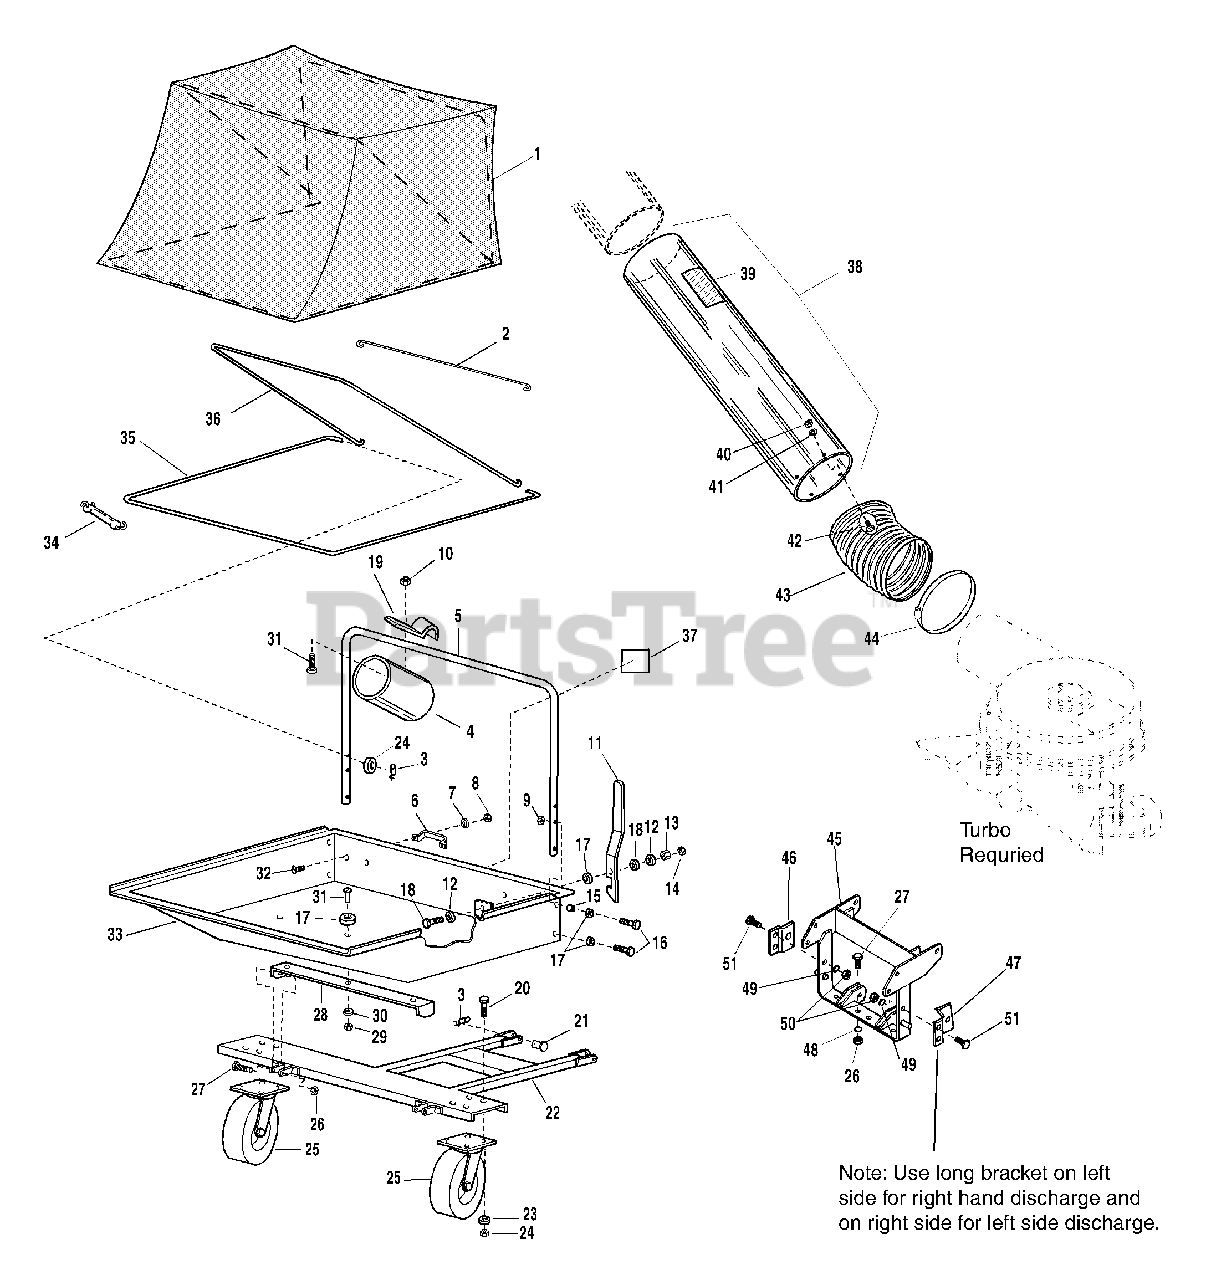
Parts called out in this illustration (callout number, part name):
1	COVER, Jrco, Cart
3	SAFETY, Pin
5	TUBE, Support
6	HANDLE, Lift
7	LOCKWASHER, Spring, 1/4-20
8	NUT, Hex, 1/4-20
9	NUT, Hex Centerlock, 5/16-18
10	NUT, Hex Nylock, 1/4-20
11	HANDLE, Latch
12	WASHER, Compression
13	NUT,Hex, 5/16-18
14	NUT, Hex Jam, 5/16-18
16	CAPSCREW, Hex Head, 5/16-18 X 1-1/2
17	WASHER, 5/16
18	CAPSCREW, Hex Head, 5/16-18 X 1-1/4
19	SLEEVE, Clamp
20	CAPSCREW, Hex Head 3/8-16 X 1
21	PIN, Rnd, Head, Drilled, 1/2 X 1-1/2
22	FRAME, Jrco, Cart
23	WASHER, 3/8
24	NUT, Hex Centerlock, 3/8-16
25	WHEEL Assembly, Swivel
26	NUT, Hex Centerlock, 1/2-13
27	CAPSCREW, Hex Head, 1/2-13 X 1-1/4
28	BRACKET, "U"
29	NUT, Hex, 5/16-18
30	LOCKWASHER, Spring, 5/16
31	SCREW, Truss Head Slotted, 5/16-18 X 3/4
32	CAPSCREW, Hex Head, 1/4-20 X 1/2
33	BOX, Jrco 44"
34	STRAP, Rubber
36	ROD, Support
37	DECAL, Maximum Capacity
38	TUBE & DECAL ASSEMBLY
39	DECAL, Cleaning Instructions
40	NUT, Hex Centerlock, #10-32
41	WASHER, Plain, #10-32
42	SCREW, Truss Head Philips, #10-32 X 1/2
43	HOSE, Vac Col, 6 X 12
44	CLAMP, Hose 6", Band Type
45	HITCH ASSEMBLY
46	BRACKET, Short
47	BRACKET, Long
48	LOCKWASHER, Spring, 1/2
49	LOCKWASHER, Spring, 5/8
50	NUT, Hex, 5/8
51	CAPSCREW, Hex Head, 5/8 1-1/4
